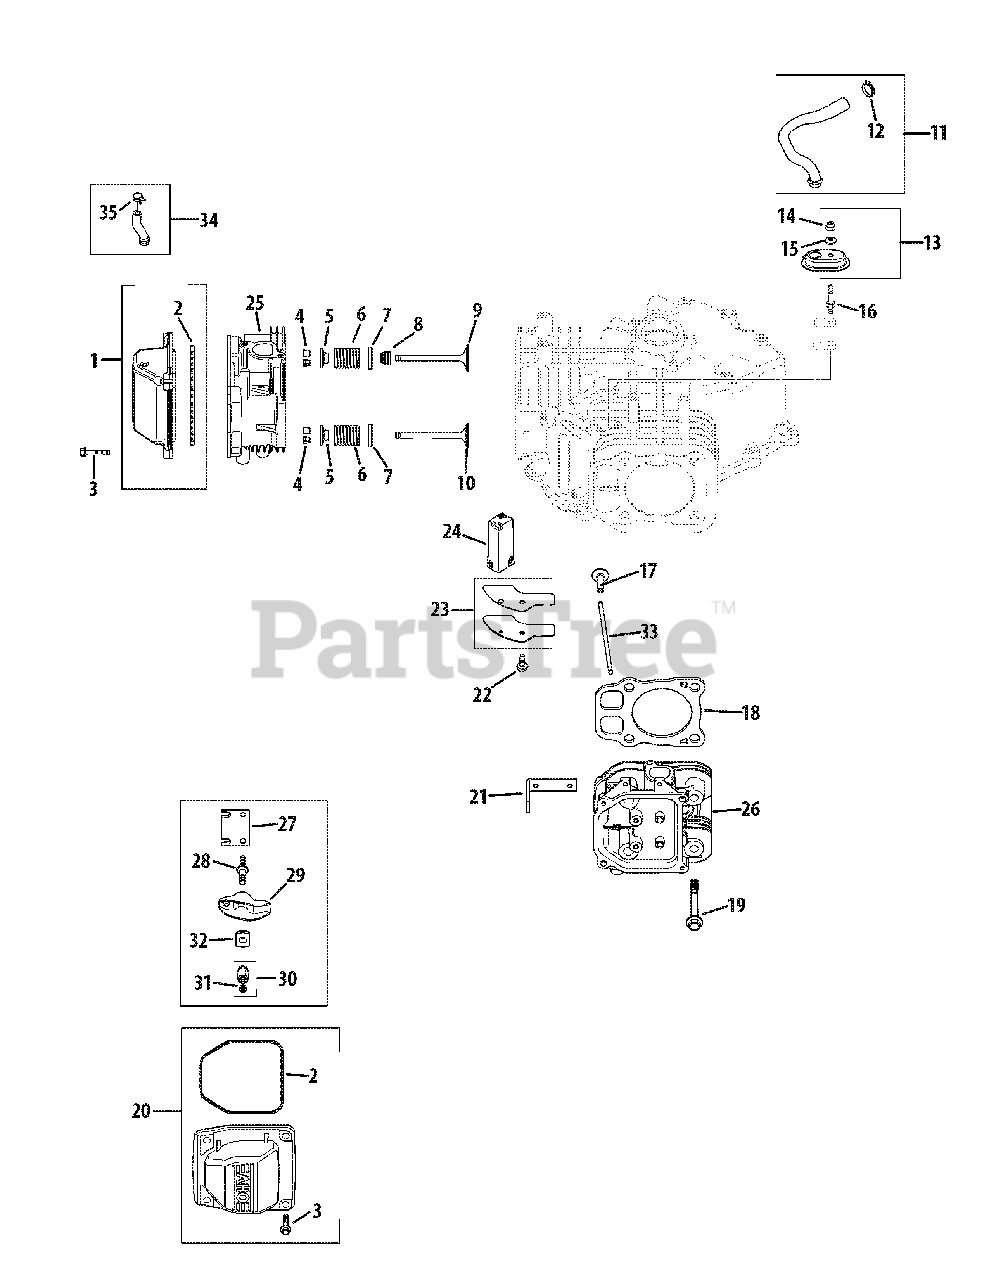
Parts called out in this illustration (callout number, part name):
1	Breather Valve Cover Kit (Inc. #2)
2	Valve Cover O-Ring
3	Flange Screw, M6 x 1.0 x 30
4	Retainer Kit
5	Valve Spring Cap
6	Valve Spring
7	Spring Retainer
8	Valve Stem Seal
9	Intake Valve (STD)
10	Exhaust Valve (STD)
11	Breather Hose Kit (Inc. #13)
12	Hose Clamp, 1.2
13	Breather Housing Kit (Inc. #15 & 16)
14	Lock Nut, M5 x .8
15	Sealing Washer
16	Breather Cover Stud
18	Cylinder Head Gasket Kit
19	Flange Screw, M10 x 1.5 x 90
20	Breather Valve Cover Kit (Inc. #2 & 3)
21	Lifting Strap
22	Flange Screw, M6 x 1.0 x 16
23	Breather Cover Kit (Inc. #32)
24	Breather Filter
25	#1 Cylinder Head Assembly Kit
26	#2 Cylinder Head Assembly Kit
30	Hex Nut Assembly (Inc. #39)
32	Rocker Arm Pivot
34	Fuel Pump Hose w/ Clamp Kit (Inc. #44)
